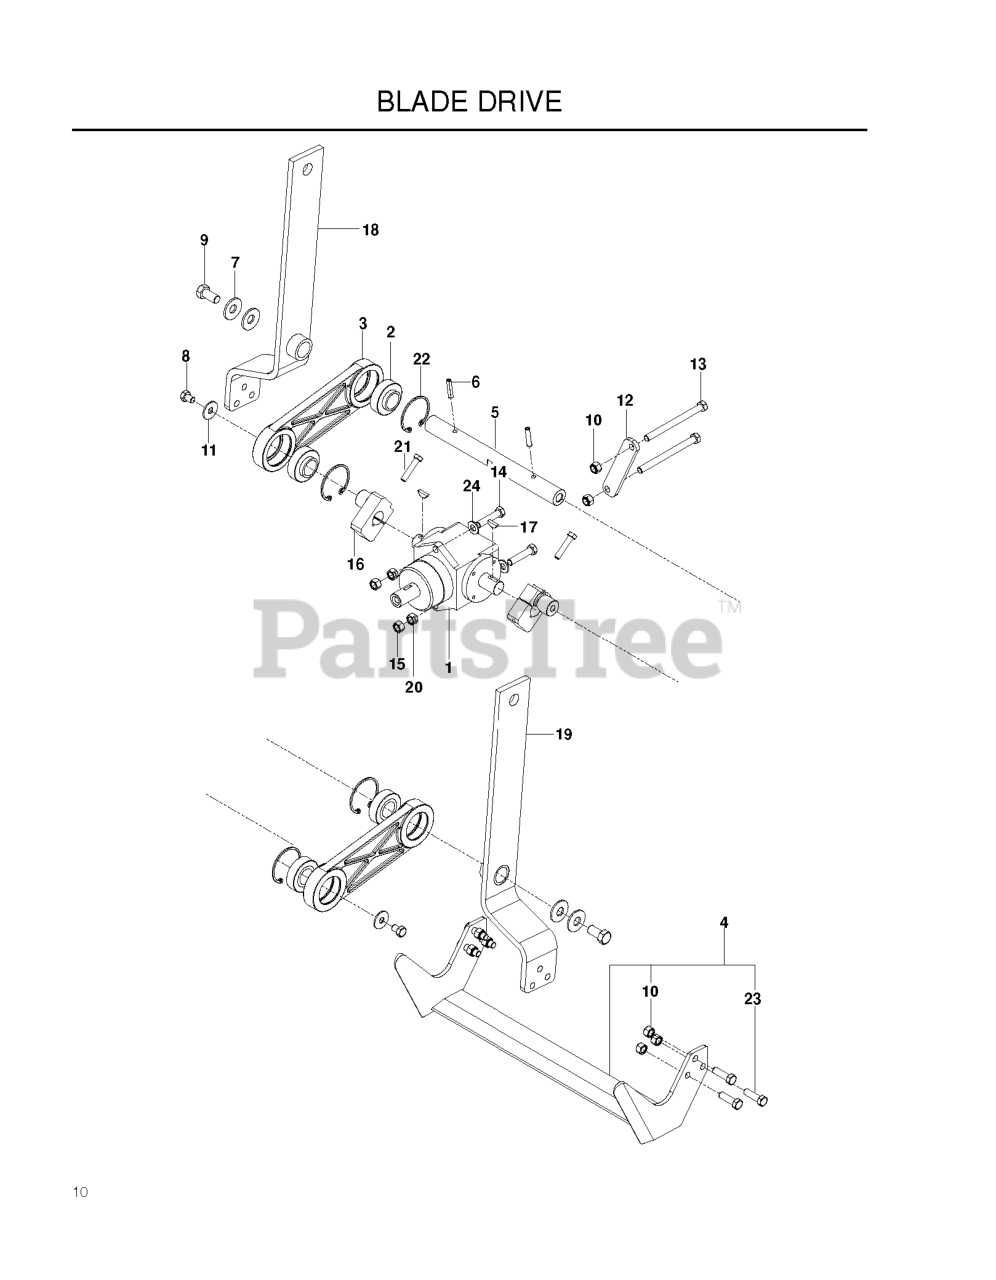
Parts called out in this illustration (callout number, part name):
1	GEAR BOX
2	BEARING
3	LINK - CONNECTING
4	KIT CUTTING BLADE 18" SOD CUT
5	SHAFT - BLADE ARM
6	SPIRAL PIN 1/4 DIA X 1.25
7	SPRING WASHER - .50
8	BOLT .375 X .5
9	HHCS 1/2-13 X 1
10	NUT 3/8-16 NYLOC
11	SPRING WASHER - .38
12	STRAP T-BOX BLACK
13	HCS 3/8C X 4 1/2
14	HCS 3/8-24
17	KEY, #9 WOODRUFF
18	BLADE ARM R.H., BLACK
19	BLADE ARM L.H., BLACK
20	NUT 3/8F CENTERLOCK
21	CAPSCREW 5/16 X 1/1/2 HEX HEAD
22	SNAP RING 52MM
23	HCS 3/8-16 X 1-1/4 GR 8 ZD
24	WASHER 3/8 SAE FLAT
